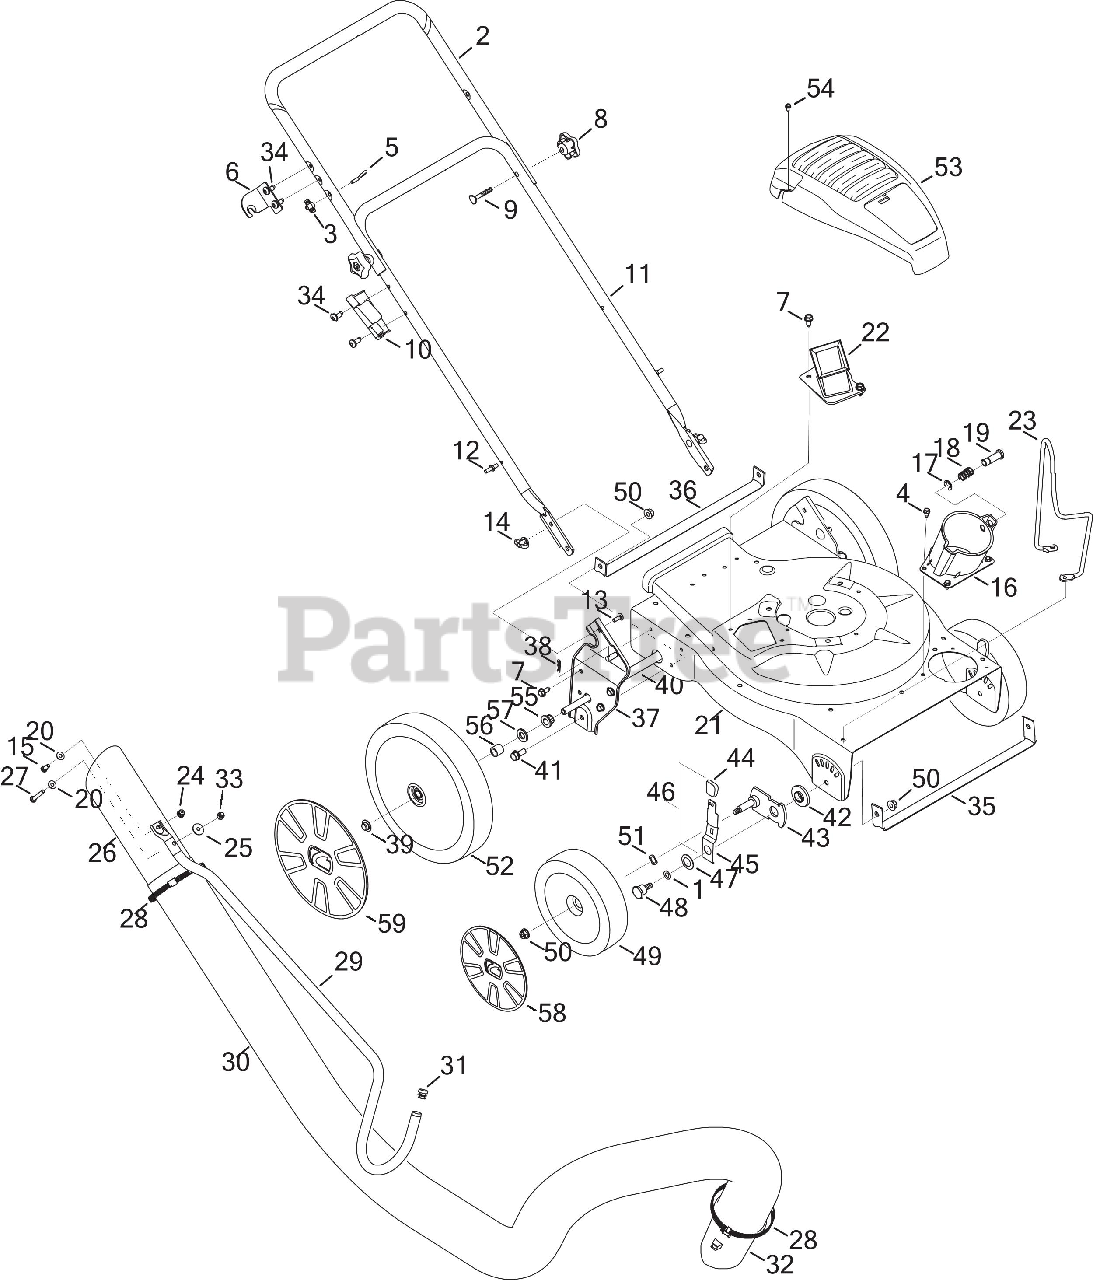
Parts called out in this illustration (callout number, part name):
1	Thrust Washer.375 ID x.70 OD
2	Upper Handle, Gullwing
4	Screw, 1/4-20 x .500
6	Upper Handle Bracket
7	Hex Cap Screw 5/16-12 x.750
9	Carriage Bolt
10	Nozzle Handle Clip
13	Carriage Screw 1/4-20 x.75
14	Wing Nut 1/4-20
15	Hex Cap Screw 1/4-20 x.620
16	Hose Base Adapter Assembly (Incl. Ref.# 17-19)
17	E Ring.500 Dia
18	Compression Spring
19	Clevis Pin
20	Flat Washer.271 ID x.630 OD
21	Upper Flail Housing
22	Chipper Chute Assembly
23	Hose Cradle
24	Flange Lock Nut, 1/4-20
26	Hose Nozzle
27	Hex Cap Screw 1/4-20 x 2.625
28	Adjustment Clamp
30	Vacuum Hose
31	Handle Plug
32	Hose Adapter
33	Cap Lock Nut, 1/4-20
34	TT Screw, 5/16-18 x .750
35	Front Wheel Support Brace
36	Rear Wheel Support Brace
37	Handle Bracket Assembly RH
37	Handle Brkt Assembly LH
38	Cotter Pin
41	HHflg, 3/8-16 x .875
42	Height Adjustment Bearing
43	Pivot Arm Assembly, Gullwing
44	Height Adjustment Knob
45	Spring Lever
46	Height Lever Assembly (Incl. Ref.# 44-45)
47	Bell Washer.760 ID x.25 OD
48	Shoulder Screw,.750 x.500
49	Wheel 8 x 2
50	Flange Lock Nut, 3/8-16
51	Washer, Wave, .531 x .781 x .013
52	Rear Wheel 8 x 2
53	Engine Shroud
54	Screw, #10-16 x 1.25
55	Brg. Flg, Hex
57	Washer, Flat, .508ID x 1.00 OD
58	Hubcap, 8”
59	Hubcap, 11”
